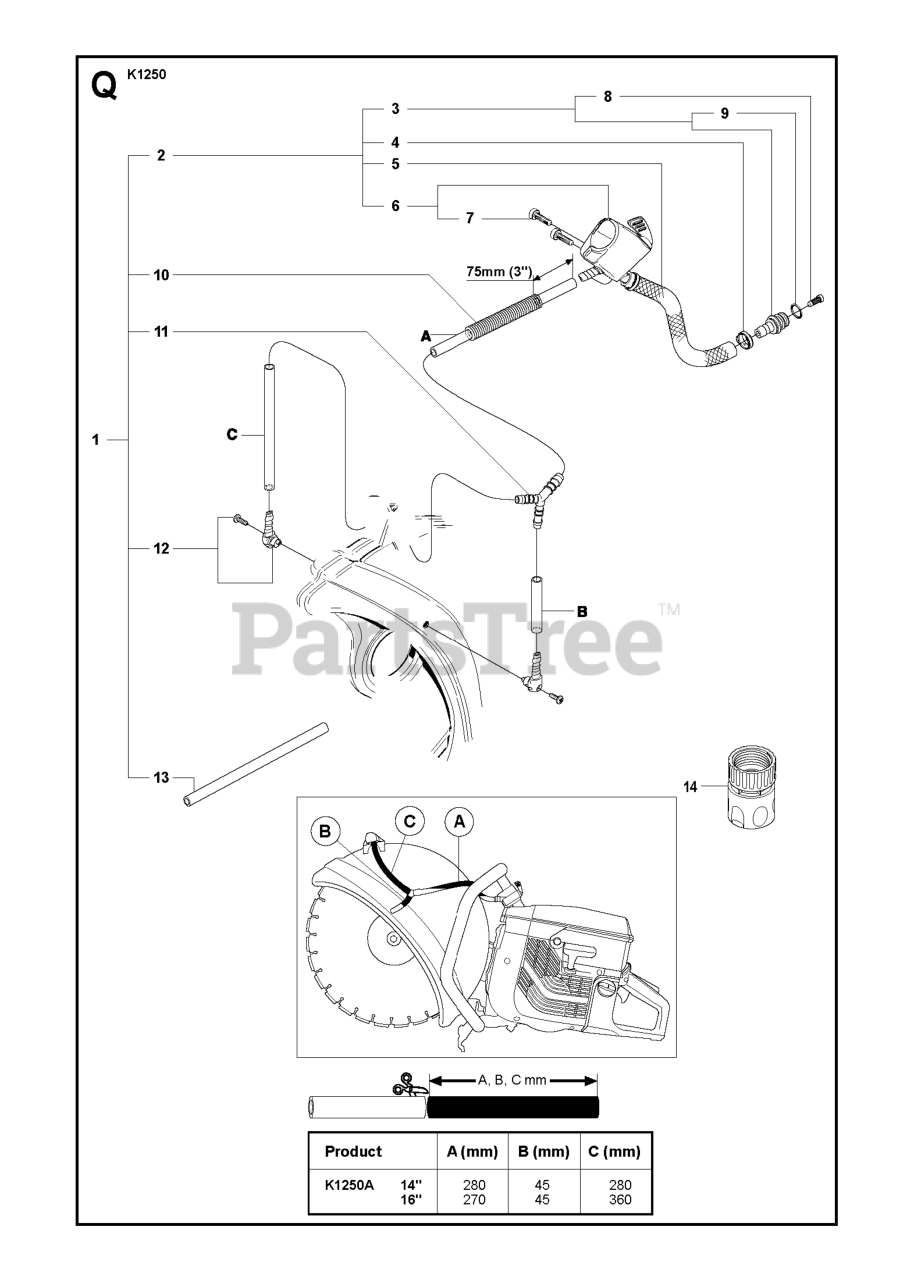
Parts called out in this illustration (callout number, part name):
1	WATER HOSE KIT
2	HOSE
4	CLAMP
5	%HOSE
6	VALVE COMPLETE
9	RP O-RING
13	RP HOSE 800MM
14	FEMALE QUICK COUPLER
